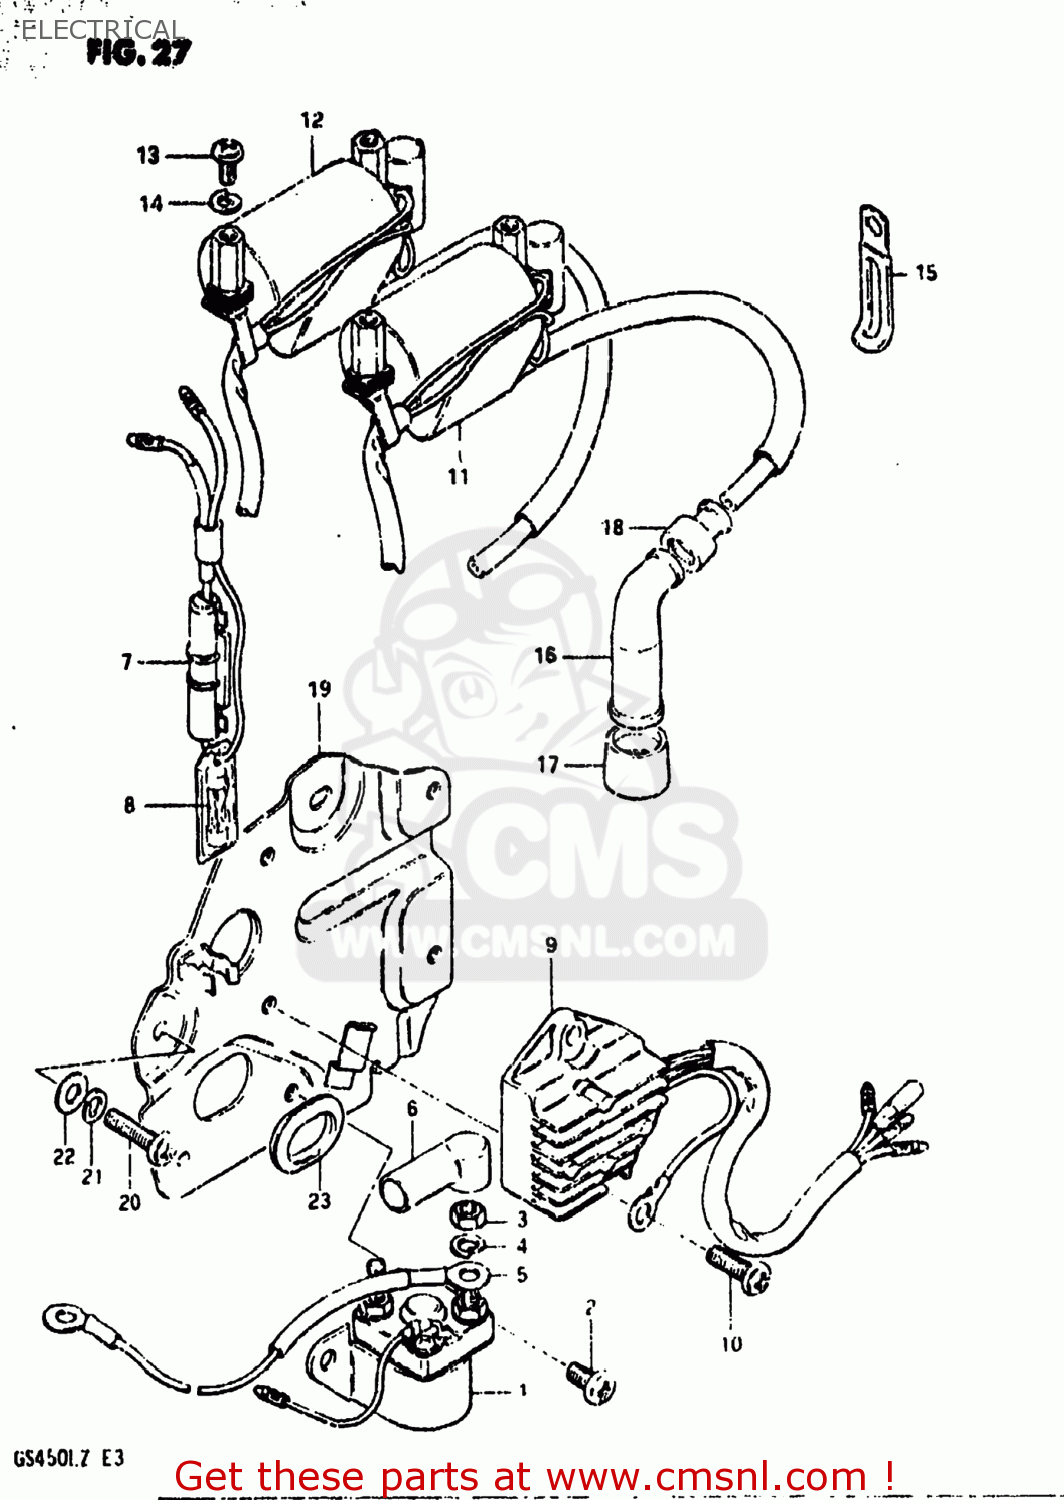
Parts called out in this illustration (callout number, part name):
1	RELAY ASSY,STARTING MOTOR
2	SCREW
3	NUT 6MM
4	LOCK WASHER
5	CORD,BATTERY MINUS
6	CAP,STARTER RELAY
7	BOX ASSEMBLY,FUSE
8	FUSE(15A)
9	RECTIFIER ASSEMBLY
10	SCREW
11	COIL ASSEMBLY,IGNITION
12	COIL ASSEMBLY,IGNITION
13	SCREW
14	LOCK WASHER
15	CLAMP
16	CAP,SPARK PLUG
17	SEAL,SPARK PLUG
18	SEAL,SPARK PLU
19	PLATE,ELECTRIC PARTS H
20	SCREW
21	LOCK WASHER
22	WASHER
23	GROMMET
